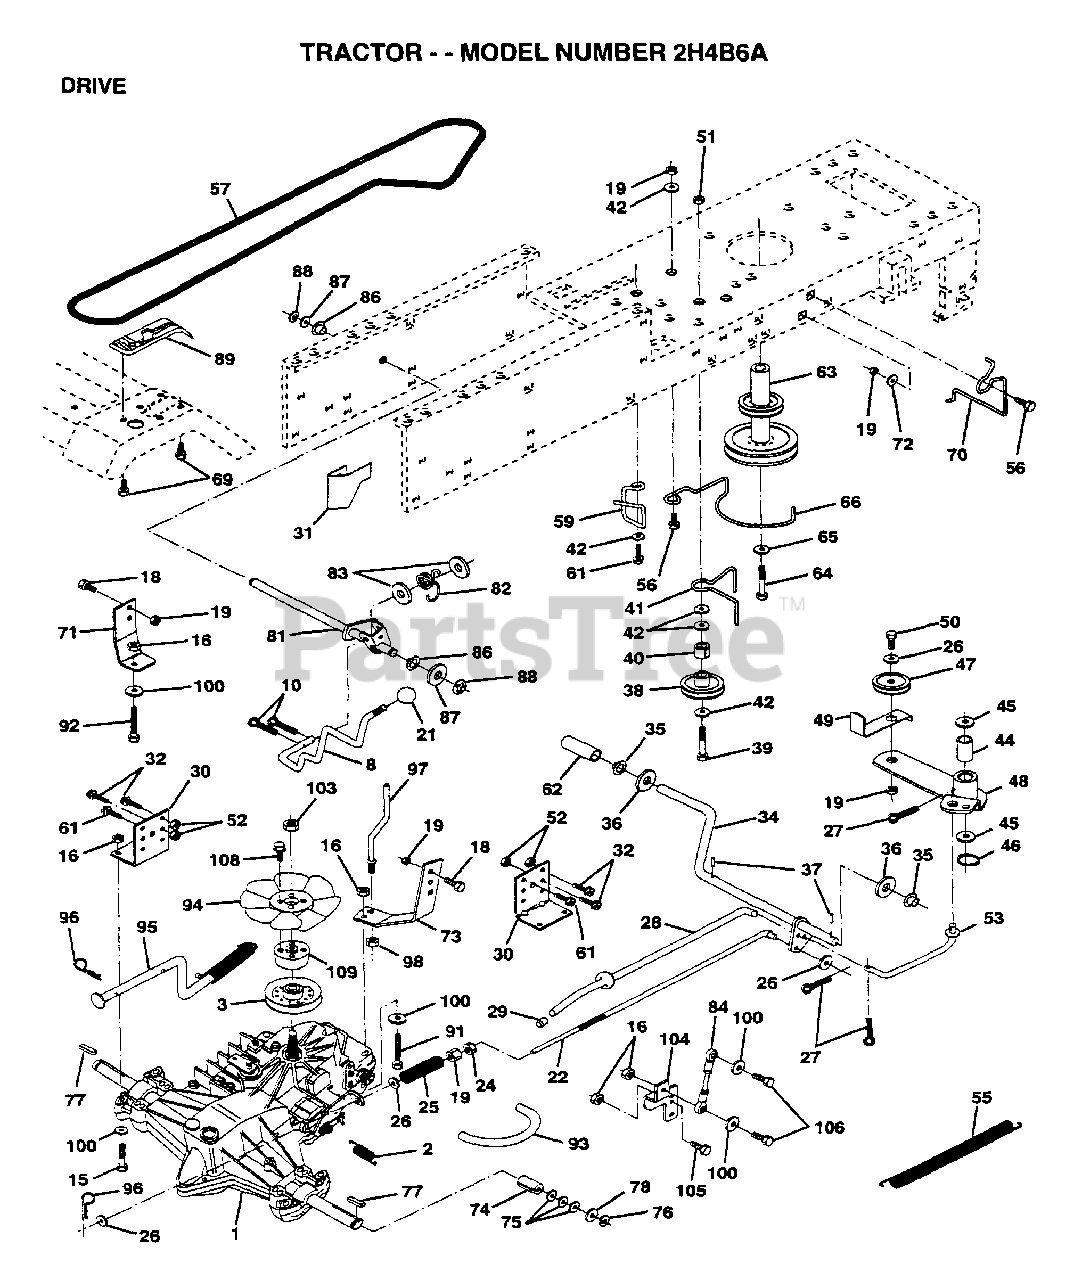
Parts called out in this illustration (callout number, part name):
1	TRANSAXLE HYD 0319-0500
2	SPRING RET BRAKE
3	PULLEY.4.20.HYDRO
8	ROD SHIFT FEND LT
15	BOLT HEX
16	NUT
18	BOLT
19	NUT
21	KNOB T (1/2-HOLE)
22	ROD.BRAKE.HYDRO.
24	NUT
24	WASHER
25	SPRING ROD LT
27	COTTER PIN
28	ROD.BRAKE.PARK.LT
29	PLUNGER CAP T
30	TRANSAXLE MTG BKT
31	"KEEPER,BELT LH T"
32	BOLT
35	NYLON BEARING
36	WASHER LT
38	PULLEY.IDLER.FLAT
39	BOLT
40	PIN COTTER 1/8
40	SPACER T
41	BELT KEEPER LT
42	WASHER
44	"LY, BEARING"
45	WASHER LT
46	KLIP RING
48	ARM IDLER
49	RETAIN BELT
53	"LINK, CLUTCH T"
55	"SPRING, RETURN LT"
57	BELT-V.HYDR.84.61
59	KEEPER BELT CNTSP
61	SCREW
62	PEDAL COVER T
63	PULLEY.ENGINE
64	BOLT
65	LOCKWASHER
66	KEEPER.BELT.ENG.L
69	SCREW HEXWSH H-L
70	KEEPER BELT ENG
71	STRAP.TORQ.LH.HYD
72	WASHER
73	STRAP.TORQ.RH.HYD
74	SPACER SPLIT
75	WASHER
76	E-RING LT
77	SQUARE KEY
78	WASHER
81	SHAFT.CROSS.HYD
82	"SPRING,TORSION"
83	WASHER
84	ROD.TIE.BALL.HYD.
86	BUSHING
87	WASHER D
88	KLIP RING
92	HEX BOLT
93	"LINE FUEL HYD 4"""
94	"FAN 7"" HYDRO"
96	RETAINER M
97	KEEPER.BELT.RH.HY
98	NUT
100	WASHER M
103	NUT NYLON 1/2-20
104	ARM.CONTROL.PUMP
105	SCREW CAP 5/16-18
106	BOLT
108	SCREW.HXHD.10-20
109	ADAPTOR.FAN.HYDRO
